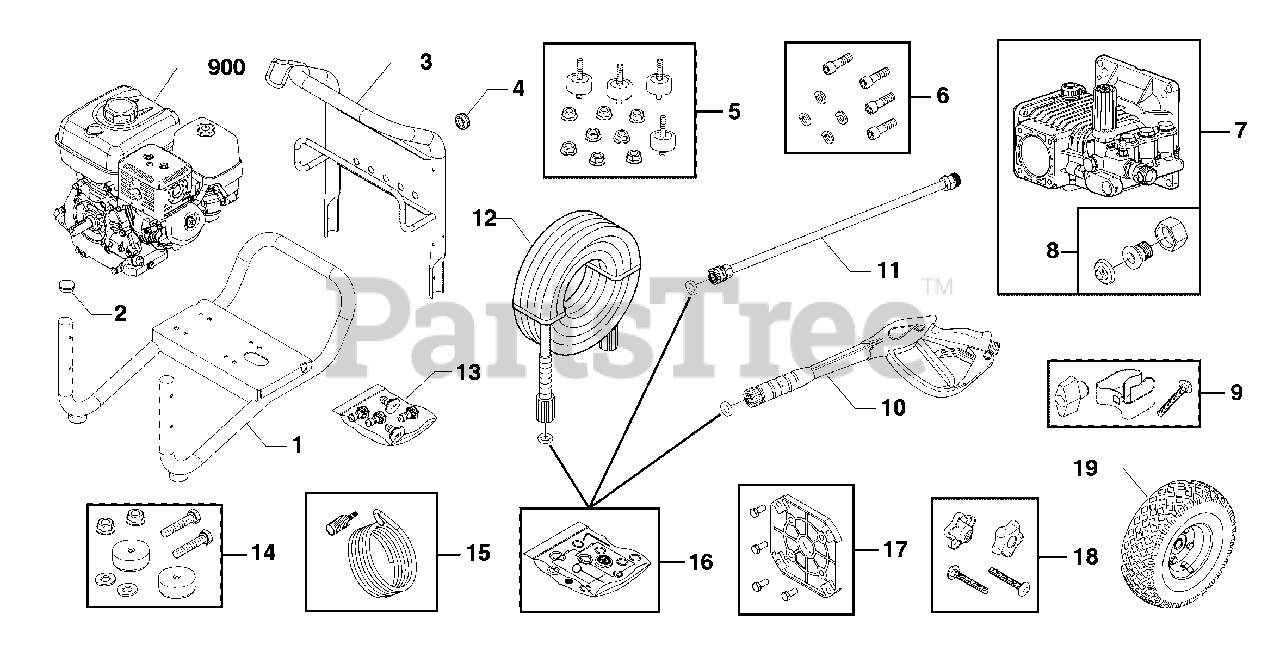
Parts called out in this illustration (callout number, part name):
1	BASE
4	GROMMET, Chemical Hose
5	KIT, Vibration Mount
6	KIT-HARDWARE PUMP MOUNTING
8	KIT, Connector, Hose, Garden
11	EXTENSION, QC
13	KIT-QC NOZZLES
14	KIT, Vibration Mount
15	KIT, Chem Hose & Filter
16	KIT-O-RING MAINTENANCE
17	KIT - ENGINE FLANGE
18	KIT-HARDWARE, HANDLE
19	WHEEL
